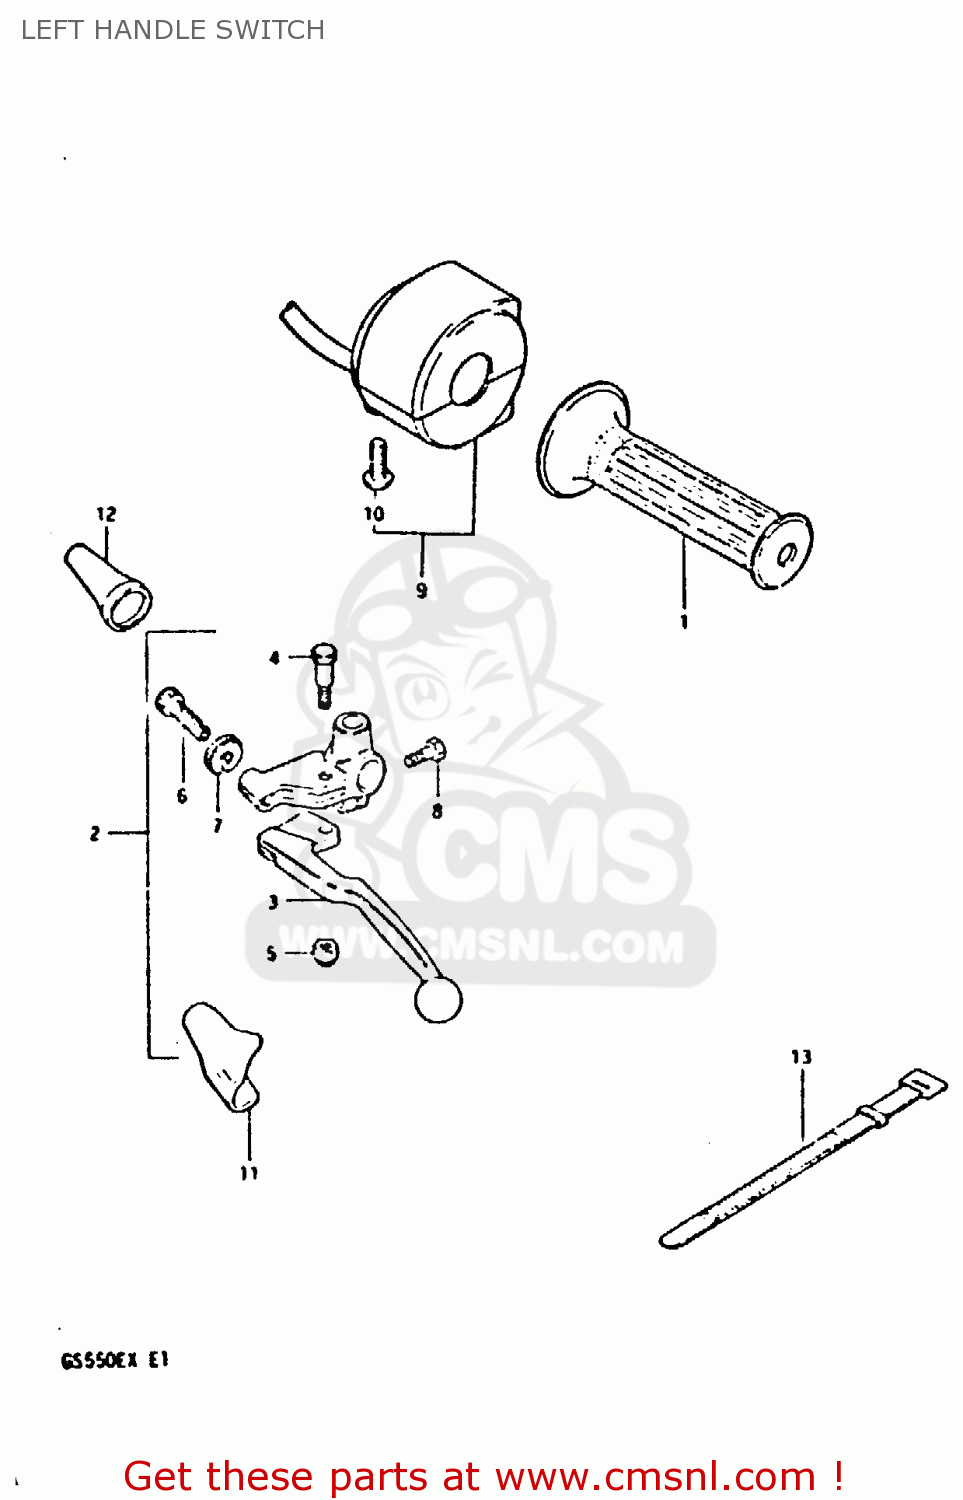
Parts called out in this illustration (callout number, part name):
1	GRIP,LEFT
2	LEVER ASSEMBLY
3	LEVER,CLUTCH
4	BOLT,LEVER
5	NUT 6MM
6	ADJUSTER,CABLE
7	NUT,CABLE ADJUSTER
8	BOLT
9	SWITCH ASSY, HANDLE LH
10	SCREW
11	COVER,CLUTCH LEVER
12	BOOT,CLUTCH CABLE
13	CLAMP(L:120)
